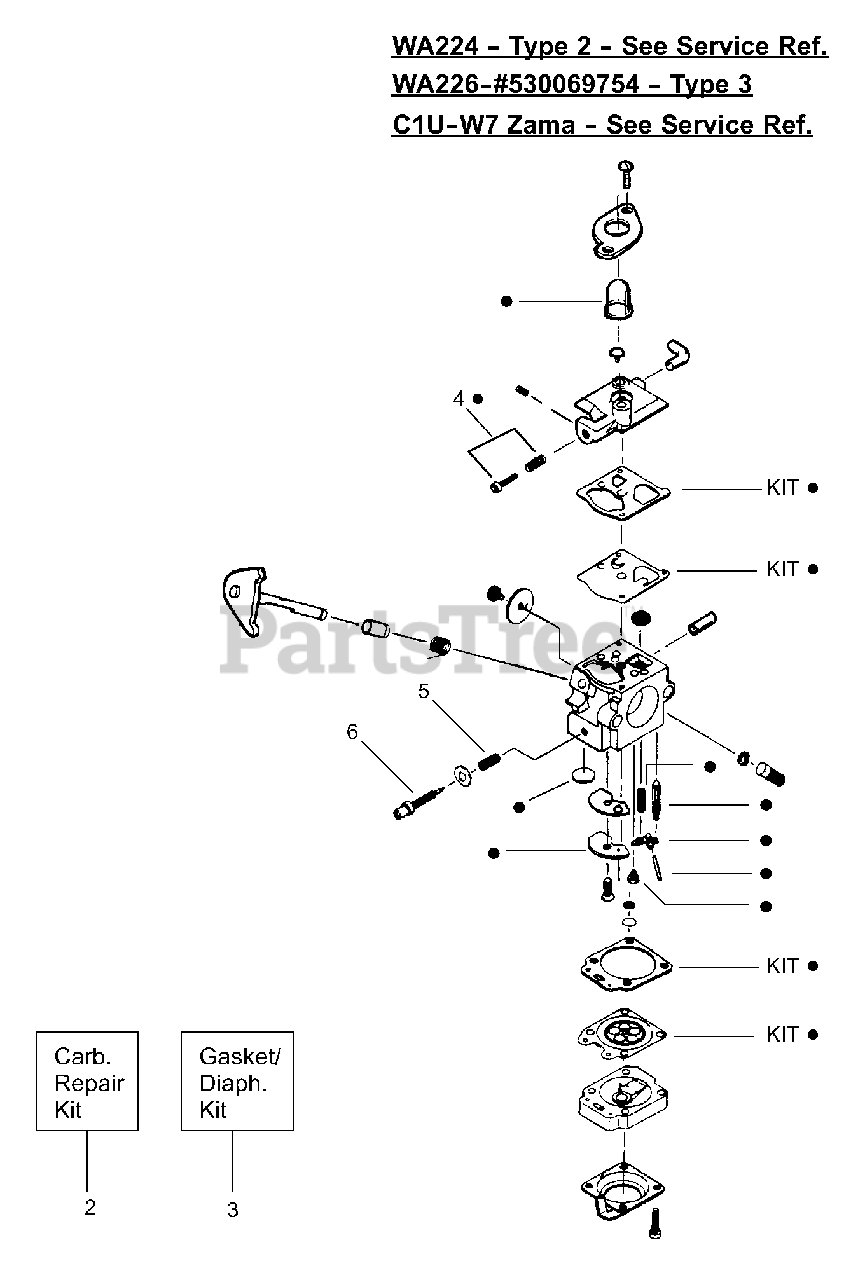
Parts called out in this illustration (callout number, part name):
2	Carburetor Repair Kit WA224 & WA226
2	Carburetor Repair Kit C1U-W7 (Zama)
3	Gasket/Diaphragm Kit WA223, WA224 & WA226
3	Gasket/Diaphragm Kit C1U-W7 (Zama)
4	Idle Screw & Spring Kit
5	Low Speed Spring
6	Low Speed Needle
530069754	Zama WA-226
